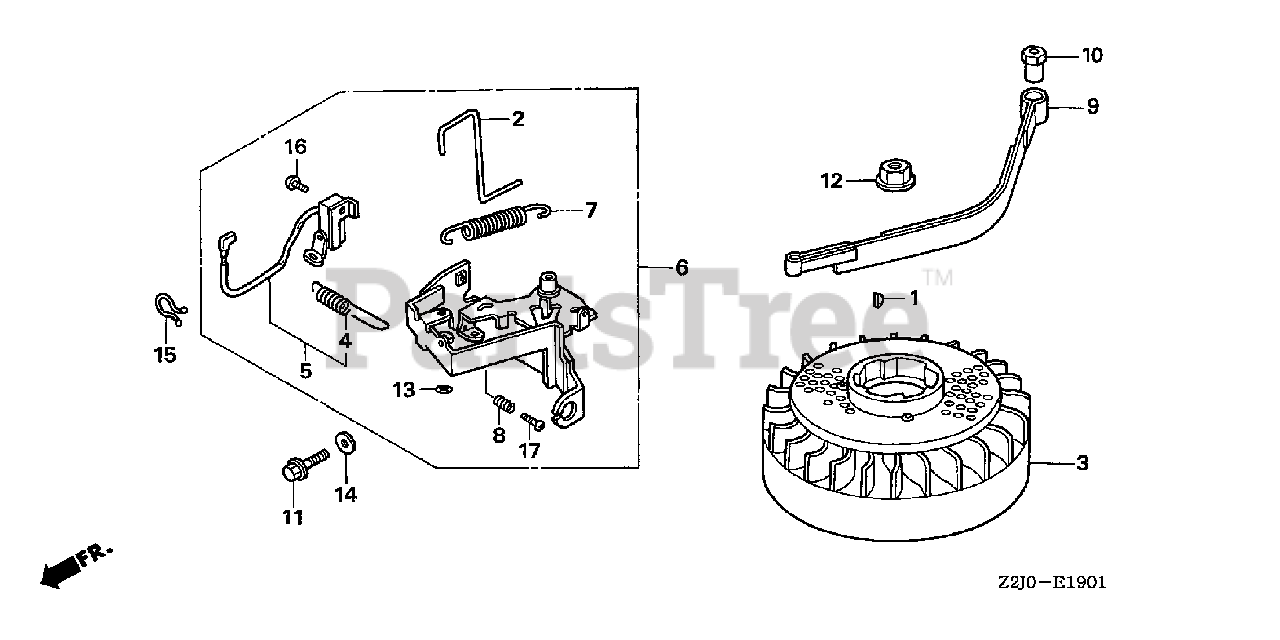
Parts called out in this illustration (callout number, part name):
1	KEY, SPECIAL WOODRUFF (25X18)
2	ROD, GOVERNOR ARM RETURN
3	FLYWHEEL ASSY.
4	SPRING, SWITCH CONTROL
5	SWITCH ASSY., ENGINE STOP
6	LEVER ASSY., BRAKE
7	SPRING, BRAKE LEVER
8	SPRING, BRAKE ADJUSTING
10	COLLAR, BRAKE SHAFT
11	BOLT, FLANGE (6X14) (CT200)
12	NUT, SPECIAL (14MM)
13	NUT, PUSH (2.6)
14	WASHER, SEALING (12MM)
15	CLIP, PURSE LOCK
16	SCREW, PAN (4X8)
17	SCREW, PAN (5X12)
